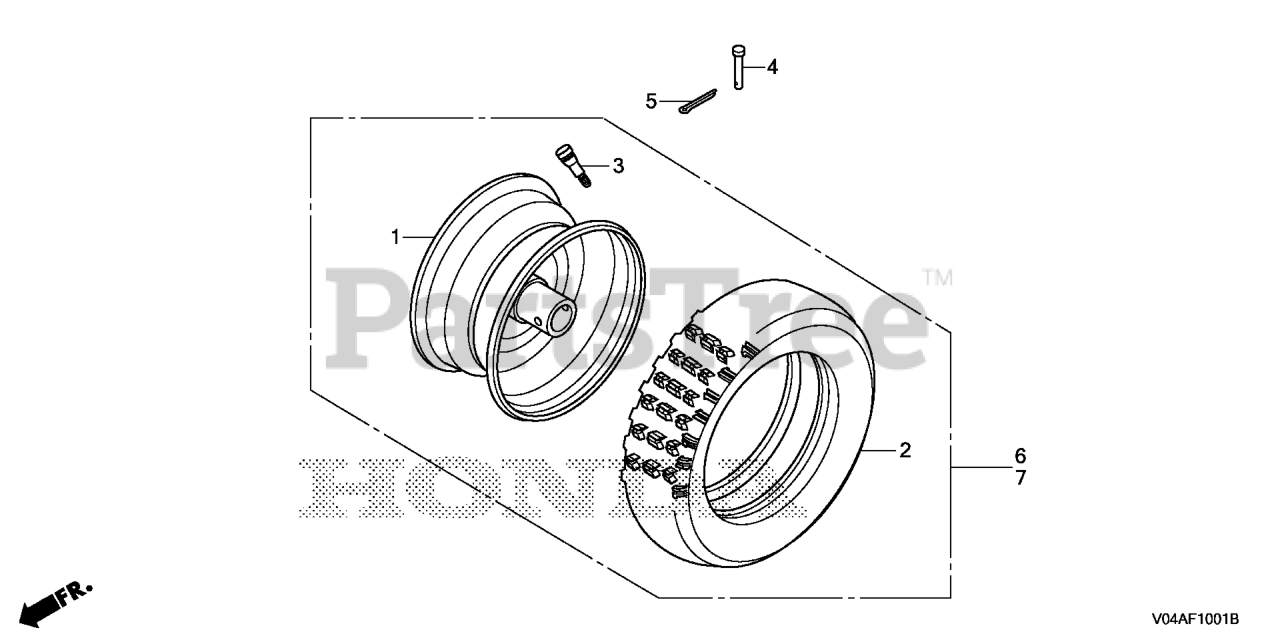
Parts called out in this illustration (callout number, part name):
2	TIRE,15X5.00-6
3	VALVE, RIM
4	PIN, CLEVIS (6.3X35)
5	PIN, COTTER (3.0X18)
6	WHEEL ASSY., R. (15X5.00-6)
7	WHEEL ASSY., L. (15X5.00-6)
